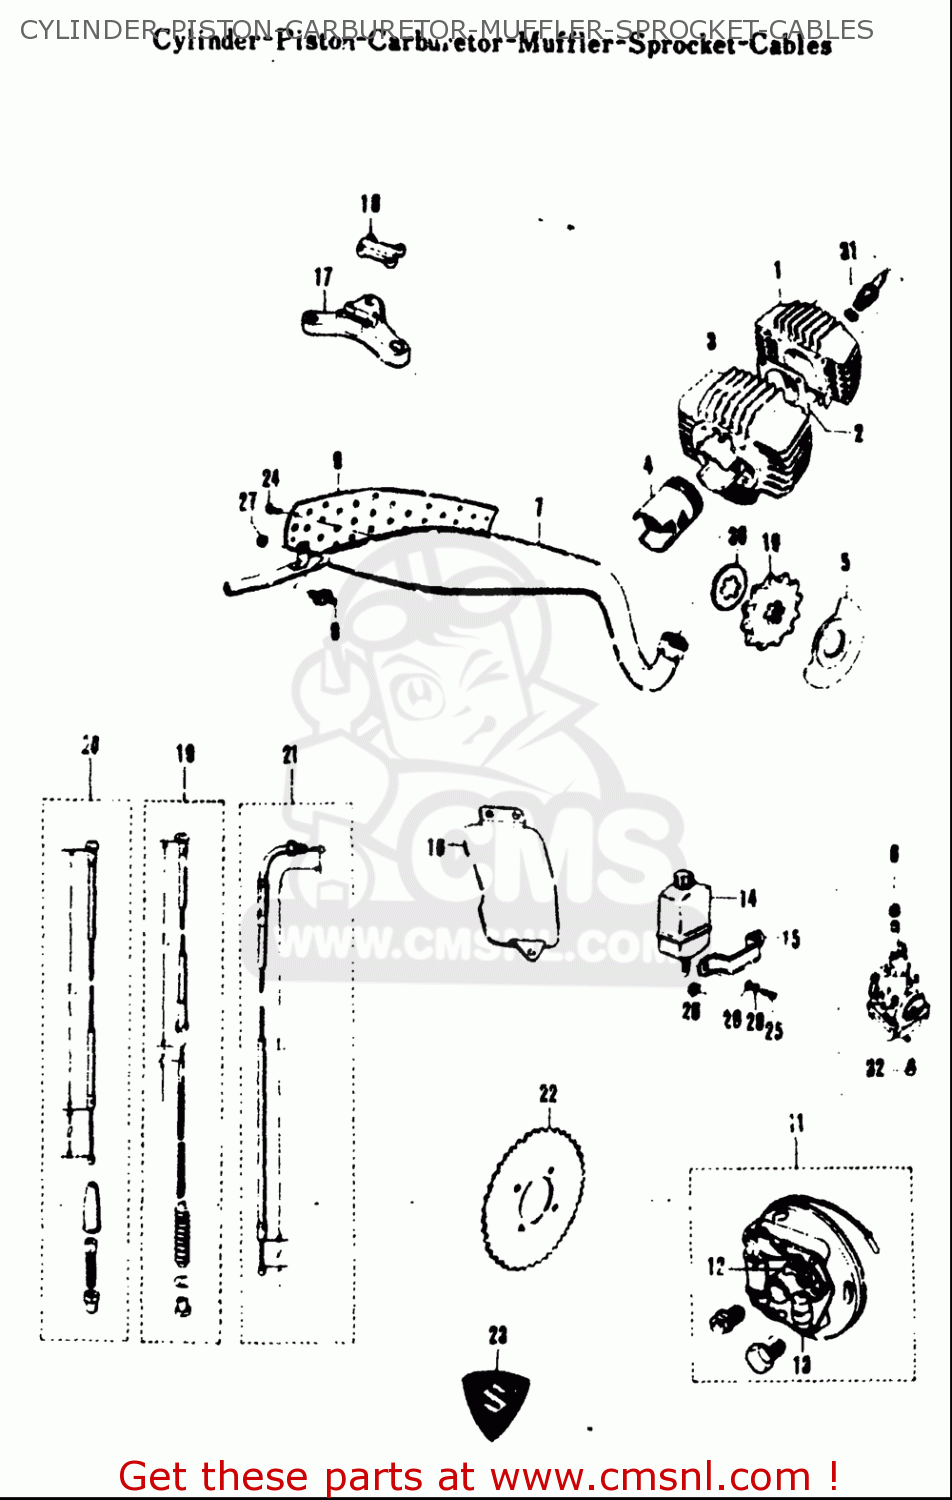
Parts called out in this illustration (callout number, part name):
10	SPROCKET,ENGINE(NT:12)
25	SCREW
26	NUT
27	NUT
28	WASHER,LOCK
29	WASHER
